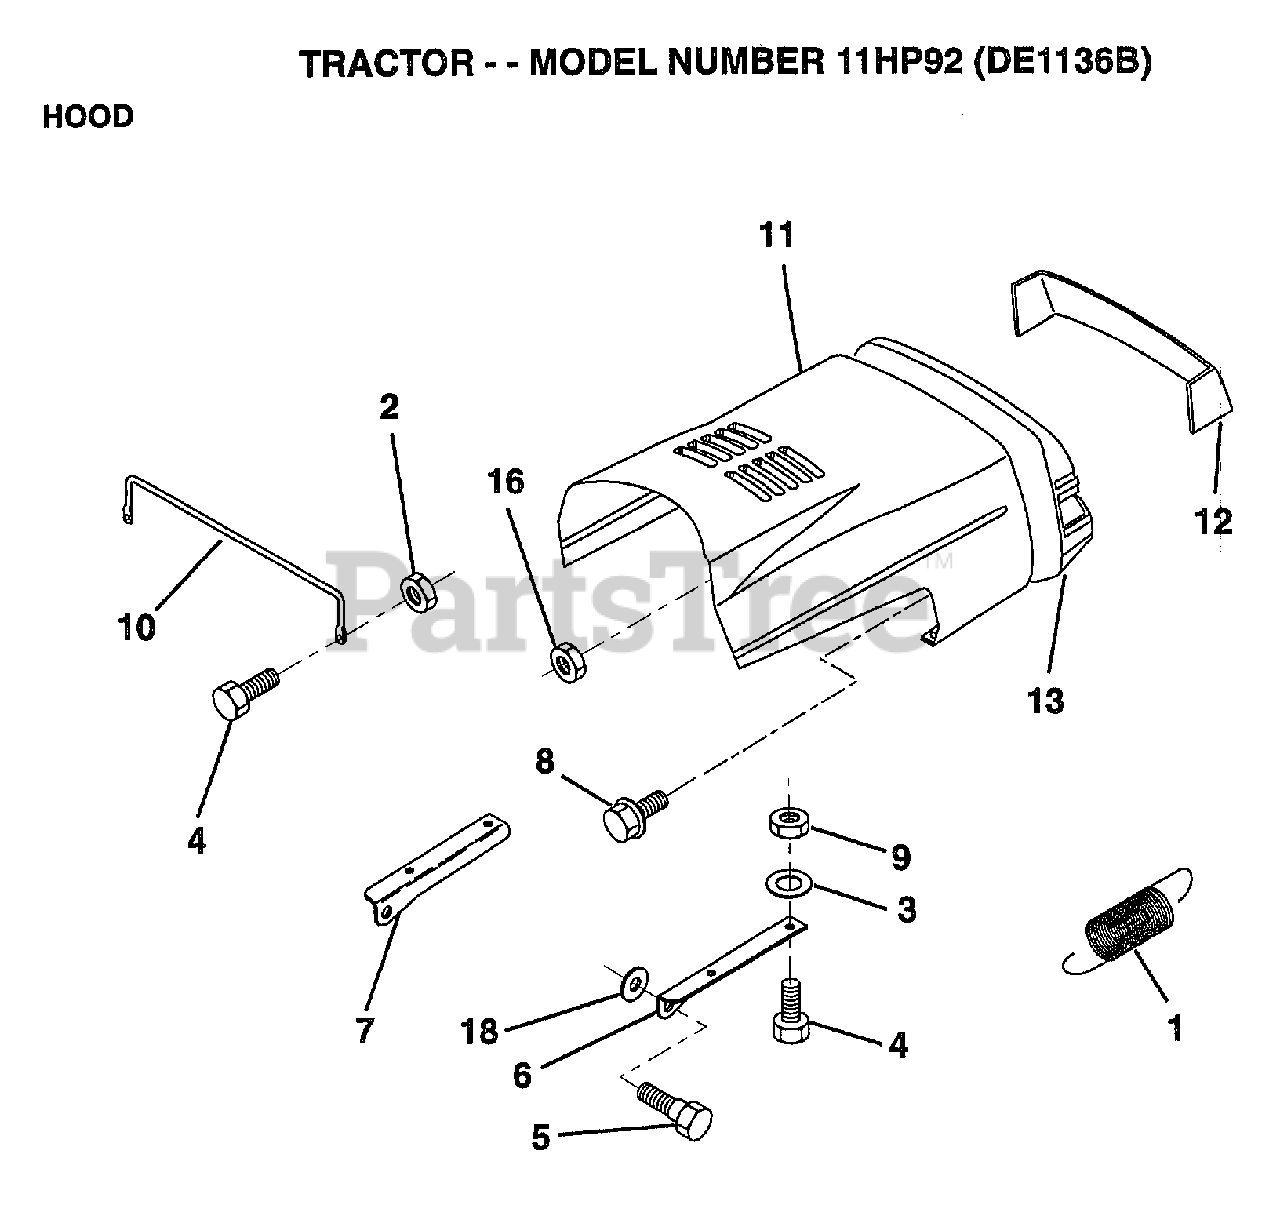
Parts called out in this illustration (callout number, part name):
1	EXT SPRING
2	NUT
3	WASHER
5	BOLT.SHLD.5/16-18
6	BRKT HOOD RH
7	BRKT HOOD LH
8	"SCREW,HWHD.HI-LO#13-16X3/4"
9	NUT
10	"BRACE,HOOD"
12	LENS.HEADLIGHT.BAR
13	GRILL
16	NUT
18	WASHER
